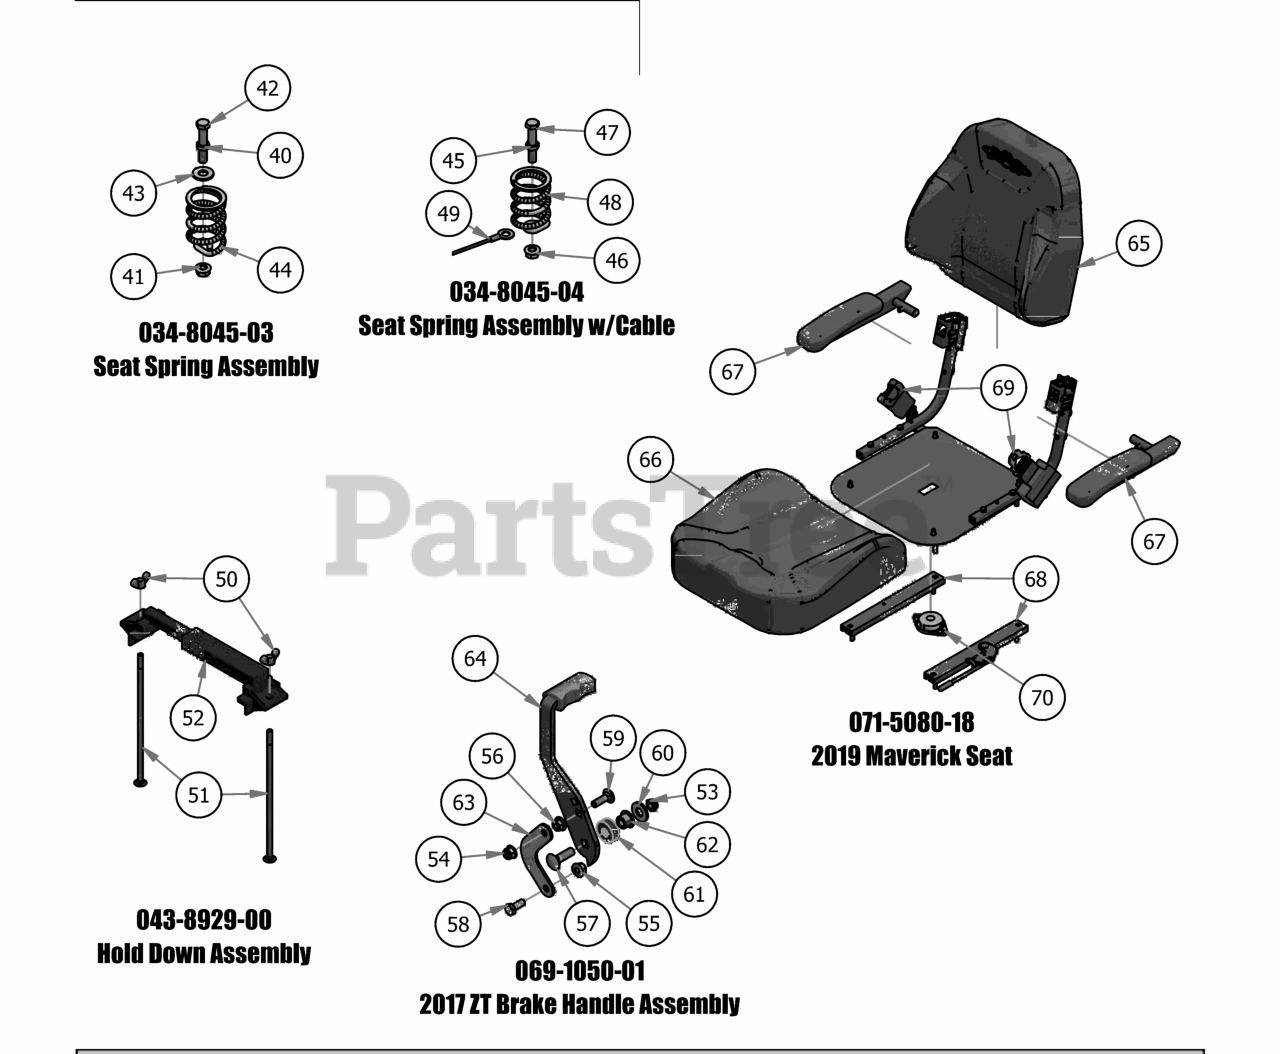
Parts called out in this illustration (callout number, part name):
40	3/8-16 Half Jam Nut
41	3/8" Flange Nut
42	3/8"-16 x 2" Gr 5 Hex Bolt
43	3/8" Flat Washer
44	Seat Spring
45	3/8-16 Half Jam Nut
46	3/8" Flange Nut
47	3/8"-16 x 2" Gr 5 Hex Bolt
48	Seat Spring
49	Seat Cable
50	1/4" Wing Nut
51	1/4-20 X 8 Carriage Bolt
52	Battery Hold Down
53	3/8-16 Centerlock Half Nut
54	5/16-18 Nylon Insert Flange Nut (Black Cap)
55	5/16" Nylon Flange Nut
56	5/16" Flange Nut
57	3/8" x 1 1/4" Carriage Bolt
58	5/16" x 3/4" Hex Bolt
59	5/16" x 1" Carriage Bolt
60	3/8" Flat Washer
61	2015 Brake Lever Spacer
62	Bronze Bushing SF-1220-8
63	Brake Cable Adapter Bracket
64	Brake Handle
65	Seat Back Cushion
66	Seat Cushion
67	Seat Arm Pair
68	Seat Rails
70	Seat Safety Switch
